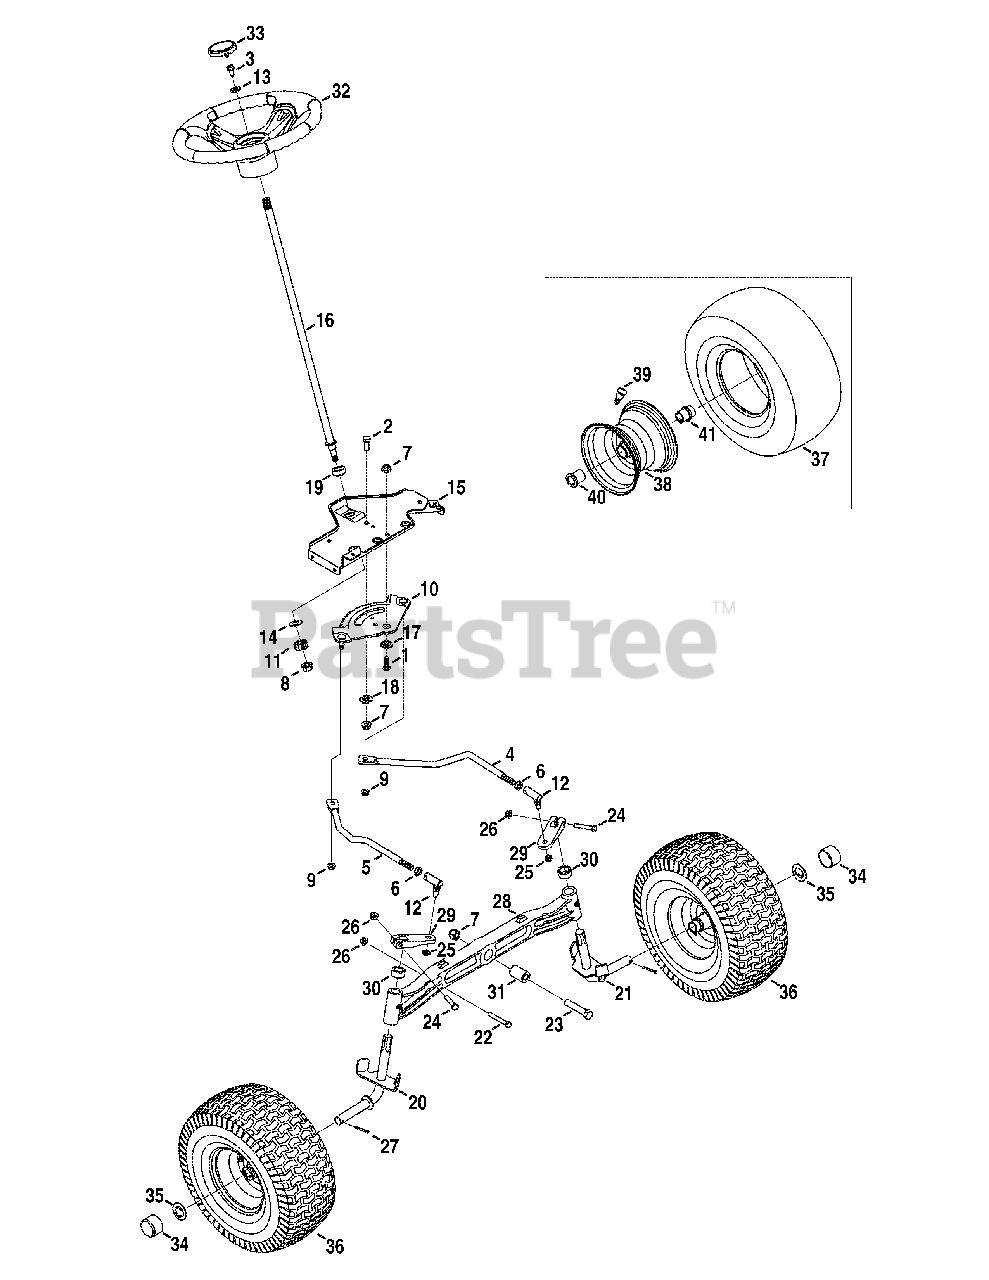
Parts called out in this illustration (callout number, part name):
1	Hex Head Screw, 3/8-16:1.00
2	Hex Head Screw, 3/8-16:1.00
3	Hex Head Screw, 5/16-18:1.00
4	LH Drag Link
5	RH Drag Link
6	Jam Nut, 7/16-20
7	Flangelock Nut, 3/8-16
8	Flangelock Nut, 7/16-20
9	Flangelock Nut, 5/16-18
10	Steering Gear
11	Steering Pinion Gear
12	Ball Joint, 7/16-20
13	Flat Washer, .406 x .875 x .105
14	Flat Washer, .51 x 1.12 x .06
15	Steering Support Bracket
15	Screw, .750 5/16-18
16	Steering Shaft, .625 OD x 24.25 LG
17	Shoulder Spacer, .385 x 1.25 x .3025
18	Spacer, .38 x 1.375
19	Hex Flange Bearing 5/8 PM
20	RH Axle Assembly
21	LH Axle Assembly
22	Hex Head Screw, 5/16-18:2.25
23	Hex Head Screw, 3/8-16:2.50
24	Hex Head Screw, 5/16-18:1.75
25	Hexlock Nut, 3/8-24
26	Flangelock Nut, 5/16-18
27	Cotter Pin, 5/32:1.25
28	Pivot Bar Axle
29	Steering Block
30	Spacer, .71 ID x .125 OD x .56LG
31	Spacer, .385 x 1.00 x 1.5075
32	Steering Wheel
33	Steering Wheel Cap
34	Bumper Cap
35	Flat Washer, .781ID x 1.590OD
36	Wheel Assembly
38	Rim Assembly
39	Tubeless Air Valve
40	Flange Bearing, .760 x 1.00 x 1.20LG
41	Flange Bearing, .760ID
